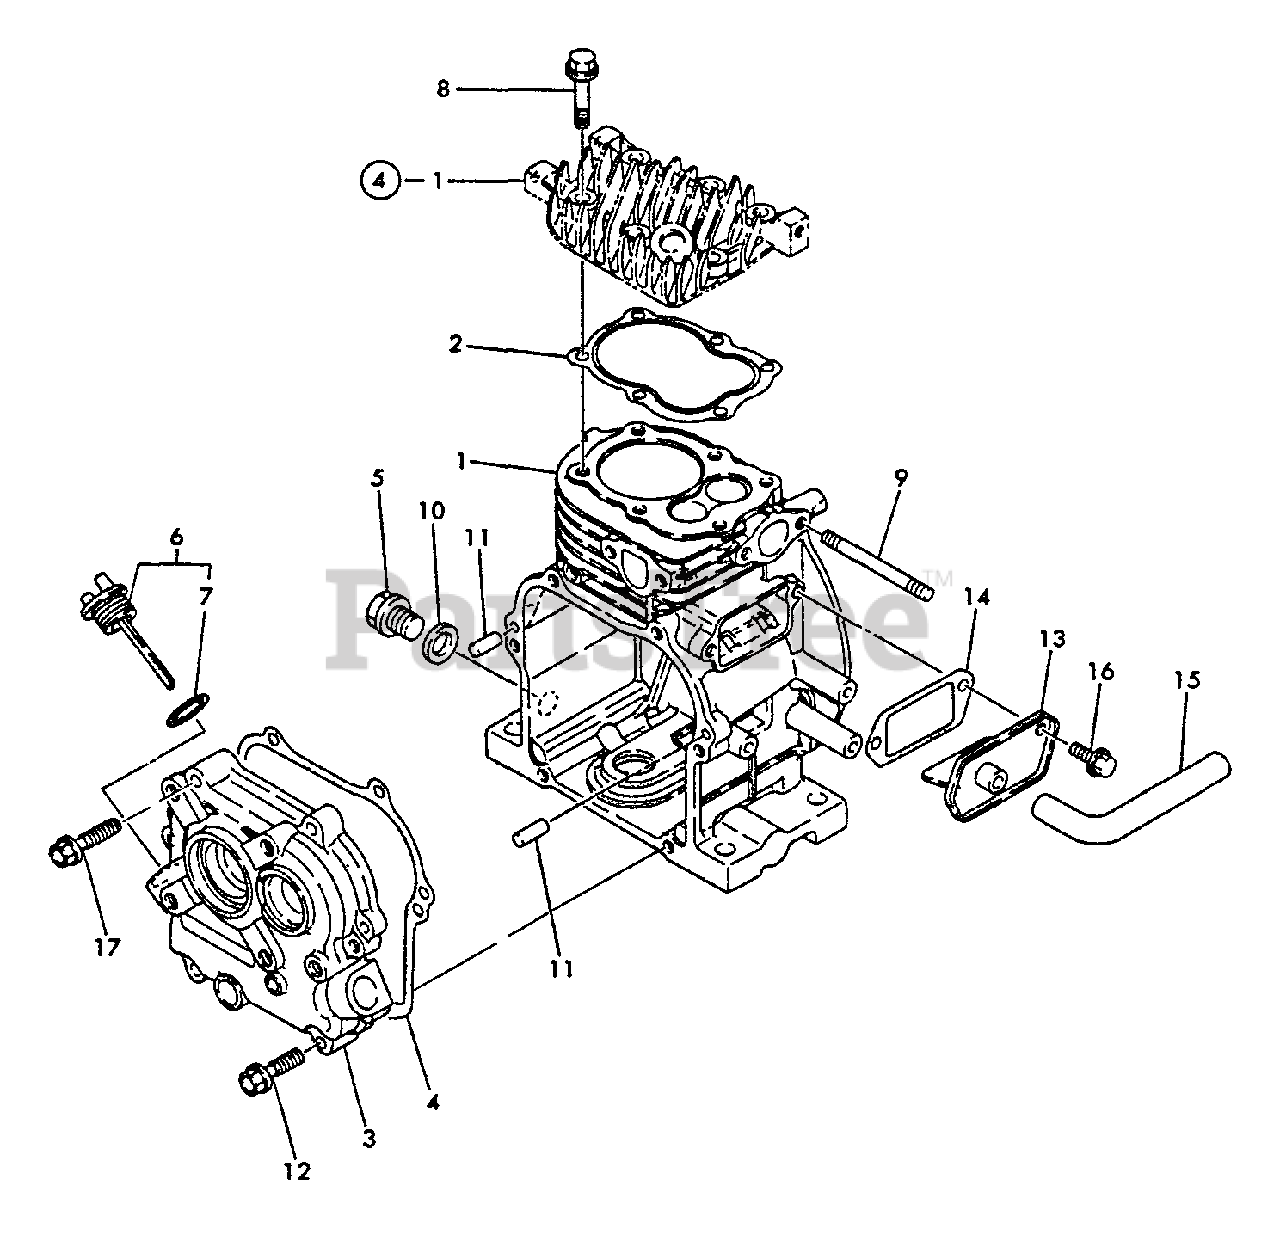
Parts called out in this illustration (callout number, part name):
1	CYLINDER ASSY
2	GASKET, CYLINDER
3	COVER, CRANKCASE
4	GASKET, CRANKCASE
5	PLUG, DRAIN
6	CAP, OIL
7	O-RING 1A P-15.0
8	BOLT - 6×35
9	BOLT - 6×70
10	GASKET
11	PARALLEL PIN 6×16
12	BOLT - 6×30
13	BREATHER ASSY
14	GASKET, BREATHER
15	PIPE, BREATHER
16	BOLT - 6×8 -- PLATED
17	BOLT - 6×32
